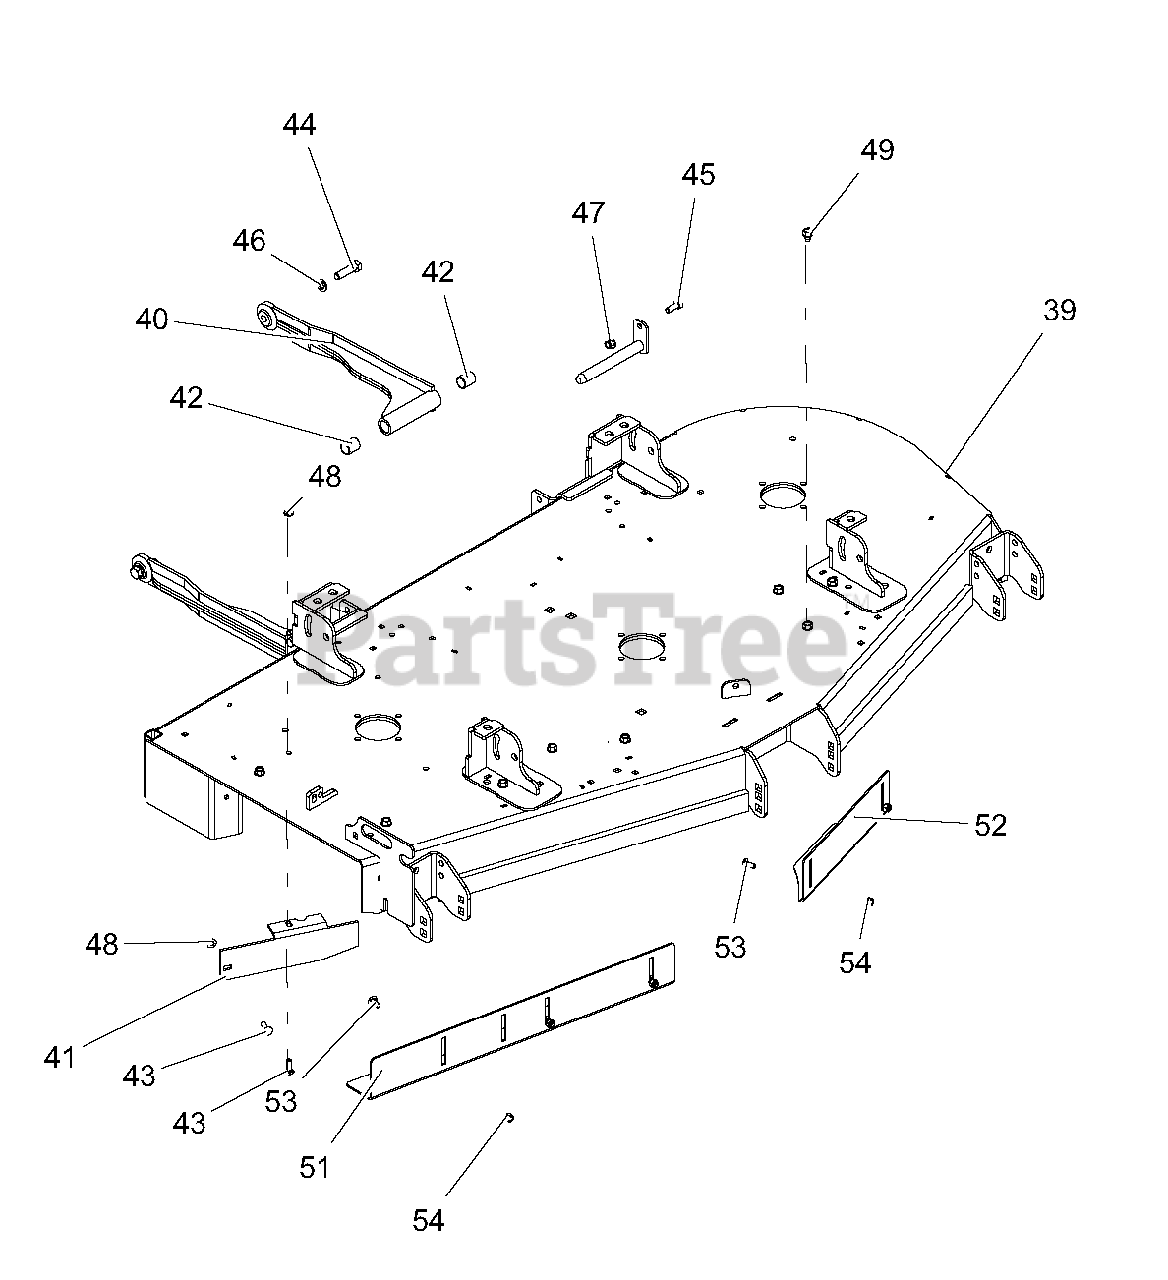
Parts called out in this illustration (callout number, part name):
39	WLDMT, 60" SIDE DISCH DECK
40	WMT, DECK STABILIZER ARM-BLACK
41	BAFFLE, 60" DISCHARGE
42	BRG, .75 X .875 X 1.00
47	NUT-LK-NYL-FLG .38-16 YWZC
48	NUT-LK-NYL-FLG .31-18 YWZC
49	SCR-TAP .38-16X.50 HWH TR YWZ
51	BAFFLE, 60" RH VACUUM
